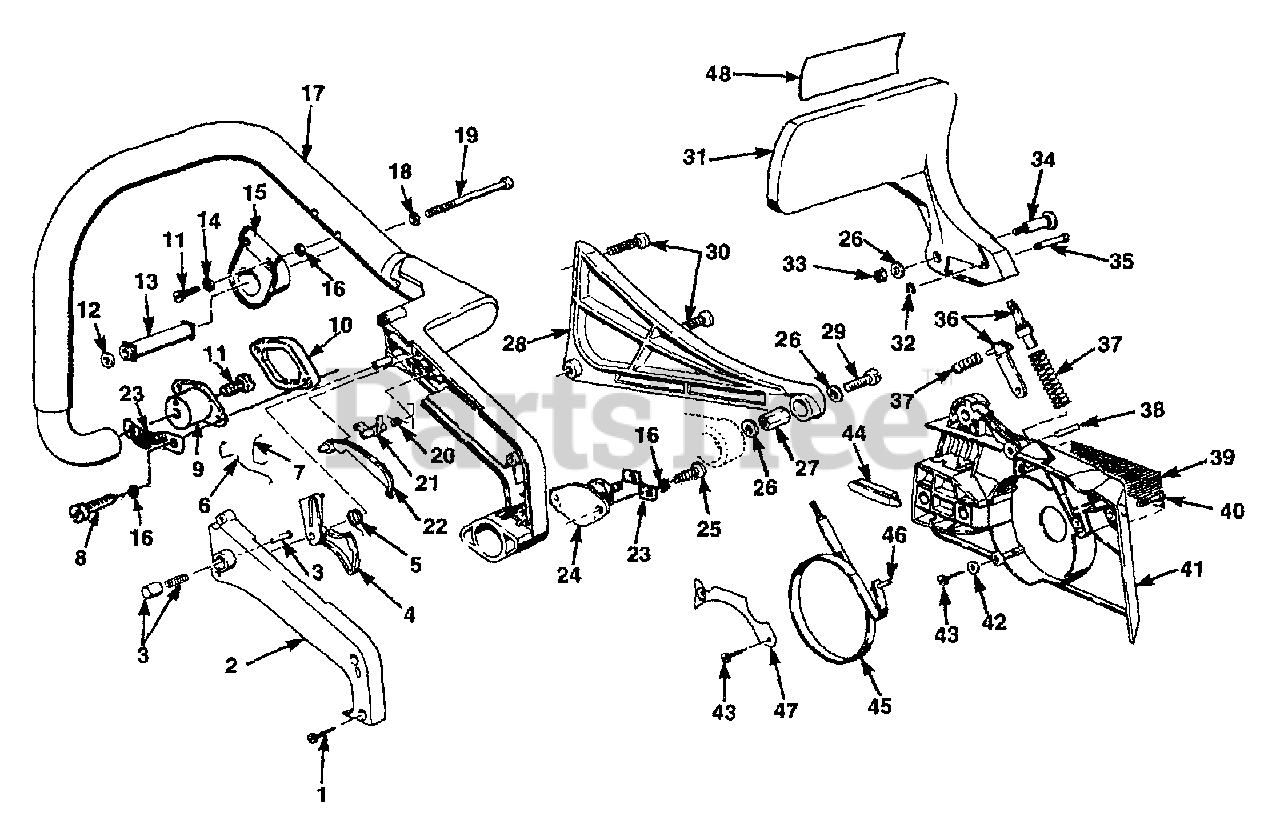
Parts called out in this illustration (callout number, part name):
1	SCREW-(3 1/2 x 19)
2	COVER-Throttle handle
3	KIT-Throttle lock
4	TRIGGER-Throttle
5	SPRING-Throttle
6	LINK-Throttle
7	LINK-Throttle
8	SCREW-(4.22 x 22)
9	ISOLATOR
10	ISOLATOR SAFETY SPACER
11	SCREW-(M5 x 12)
12	WASHER-Flat
13	SPACER-Isolator
14	WASHER-Lock
15	HANDLE BAR ISOLATOR
17	HANDLE BAR ASSEMBLY
18	WASHER-Lock
19	SCREW-(M6 x 65)
20	SPRING-Torsion
21	LEVER-Throttle lock
22	LOCK-Throttle
23	STRAP-Isolator
24	ISOLATOR
25	SCREW (4.2 x 16)
26	WASHER-Lock
28	HAND GUARD (rear)
29	BOLT (M5 x 10)
30	SCREW (4 x 20)
31	HAND GUARD
32	RING-Retaining
34	SCREW-Shoulder
36	ADJUSTMENT SET
37	SPRING SET
39	DECAL-Homelite
40	SCREW-(5 x 20)
41	DRIVE CASE COVER ASSEMBLY
43	SCREW (3.5 x 13)
44	GUIDE-Chain
45	BRAKE BAND ASSEMBLY
46	PIN-Dowel
47	COVER-Plate
